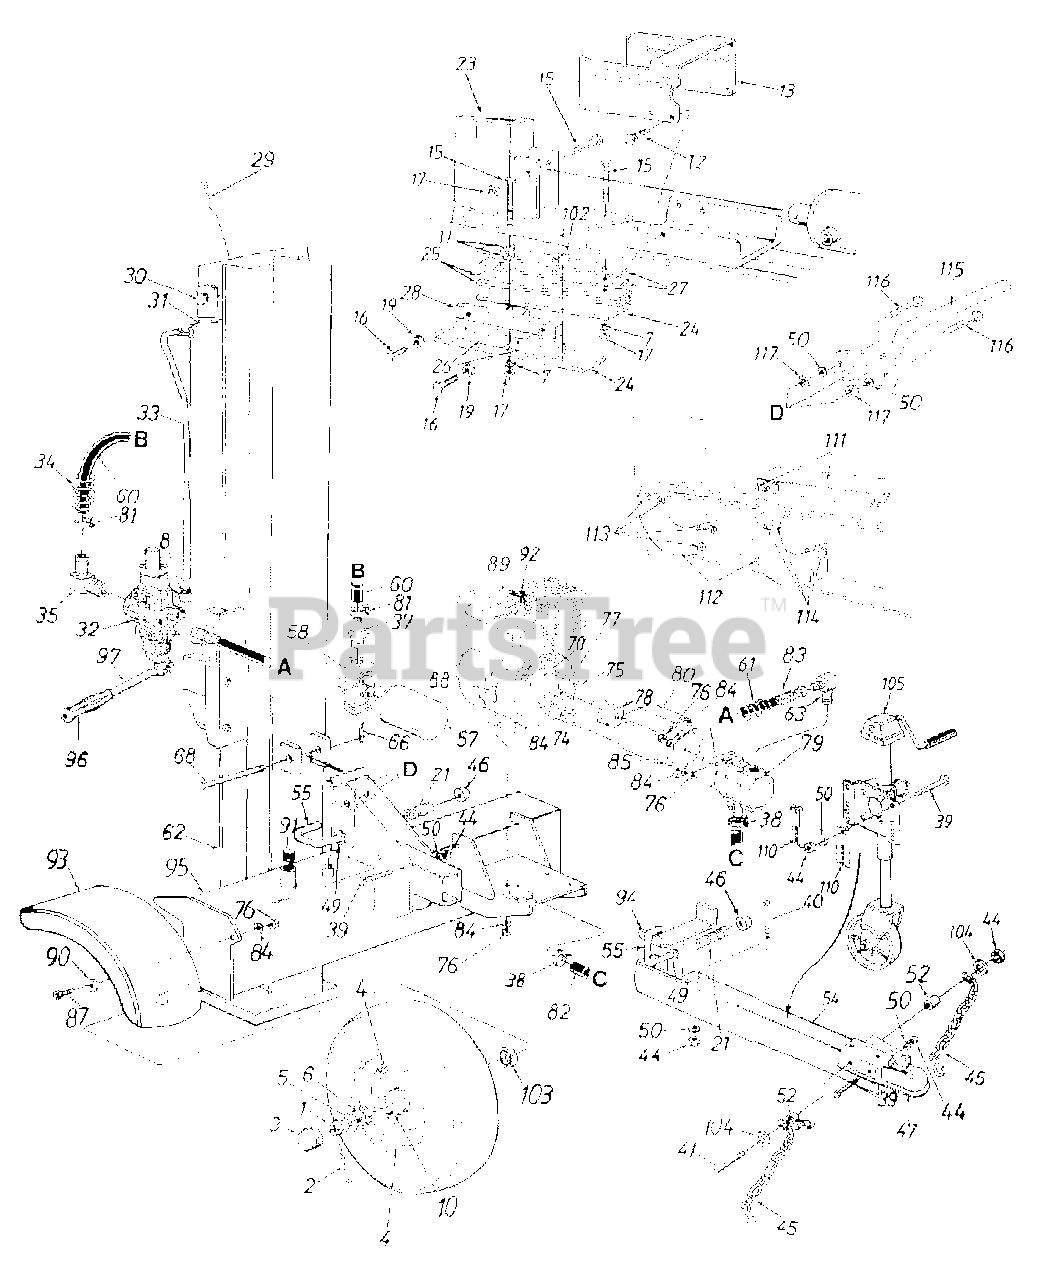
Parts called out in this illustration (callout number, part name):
1	Slotted Nut 3/4-16 Thd.
2	Cotter Pin 5/32" Dia.
5	Fl-Wash. .76" I.D. x 1.5" O.D.
6	Bearing Cone
7	L-Wash. 1/2" I.D.
8	90° Solid Male Adapter
10	Bearing Cup
11	Fl-Wash. .531" I.D. x .94" O.D.
12	Hex Cap Scr. 3/8-16 x 1" Lg.
15	Hex Bolt 1/2-20 x 2.75" Lg. (Grade 8)
16	Hex Bolt 3/8-24 x 1.5" Lg.
17	Hex L-Nut 1/2-20 Thd.
19	Hex Jam Nut 3/8-24 Thd. (Grade 5)
21	Comp. Spring 4" Lg.
26	Adjustable Gib
30	Cylinder Mounting Pin
31	Kit Seal 5.0" for Best Metals cylinder 718-0313
31	Hydraulic Cylinder
31	Kit Seal 5.0" for XINGHUI cylinder 718-0313A
31	Kit Seal 5.0" for ENERGY cylinder 718-0313A
33	Metal Pressure Tube
34	Hose Guard
35	Return Elbow
37	3/4" Hose Barb.
38	Hose Clamp 1.5" O.D.
39	Hex Bolt 3/8-16 x 3" Lg. (Grade 8)
40	Hex Bolt 3/8-16 x 4.75" Lg.
41	Hex Bolt 3/8-16 x 4.25" Lg.
44	Lock Nut 3/8-16 (585)
45	Chain-Tow Hitch
47	Hitch Coupler
49	Fl-Wash. .635" I.D. x .93" O.D.
50	L-Wash. 3/8" I.D.
52	Spacer .445" Lg.
57	Filter Element
58	Filter Head
60	Return Hose 3/4" I.D. x 44" Lg.
61	Hose Guard
66	Cotter Pin 1/8" Dia.
68	Hinge Pin 1/2 x 4.8" Lg.
74	Hex Bolt 5/16-24 x .62" Lg.
75	Hex Bolt 5/16-24 x 5.25" Lg.
76	Hex Nut 5/16-24 Thd.
77	Sq.-Key 1/4" x 2" Lg.
78	Flexible Coupling
79	Gear Pump
80	Coupling Shield
81	Hose Clamp 5/8"
82	Suction Hose 1" I.D.
83	High Pressure Hydraulic Hose
84	L-Wash. 5/16" I.D.
87	Hex Bolt 5/16-24 x .75" Lg.
88	Hex Bolt 5/16-24 x 1.75" Lg.
89	Engine
90	Fl-Wash. .344" I.D. x .875" O.D.
91	L-Vent Pipe Plug
92	Spark Plug Boot
97	Control Handle
102	Spacer 1/2" I.D. x .86" Lg.
103	Bearing Seal Only
104	Fl-Wash. 3/8" I.D. x .87" O.D.
105	Jack Stand
114	Carriage Bolt 3/8-16 x 1" Lg.
117	Hex Nut 3/8-16 Thd.
